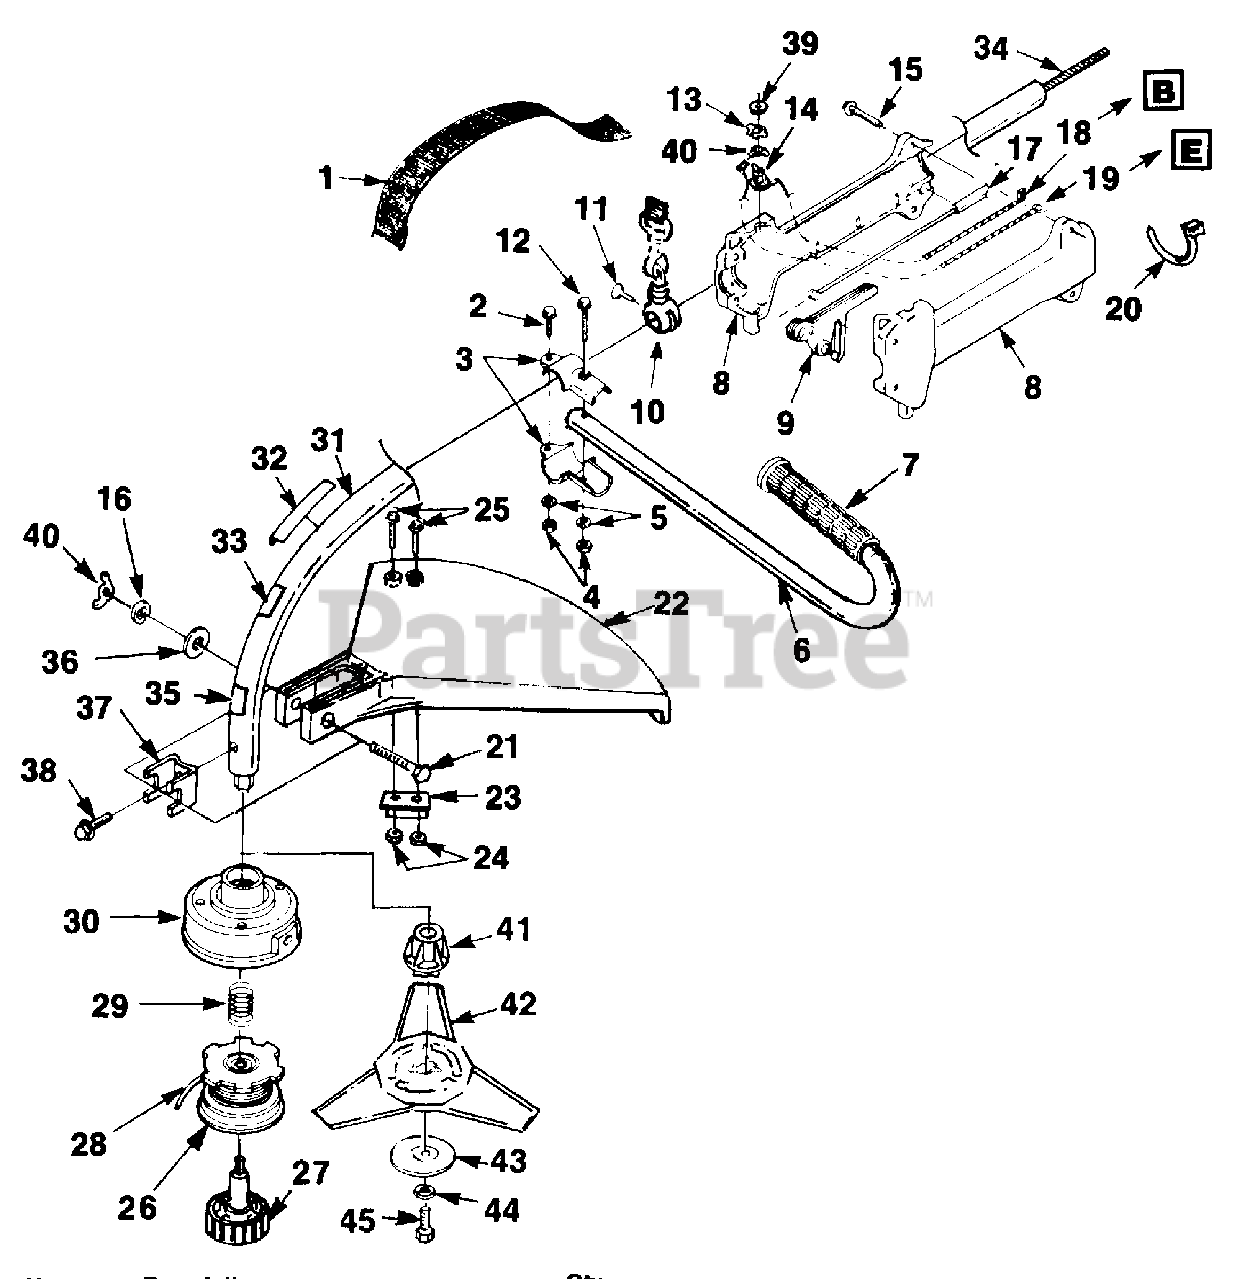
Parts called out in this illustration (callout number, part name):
2	SCREW (1/4-20 x 7/8")
3	CLAMP- Handle bar
4	NUT (1/4-20)
5	WASHER (1/4")
6	HANDLE BAR
8	HANDLE GRIP ASSY.
9	TRIGGER
10	BRACKET- Hanger
11	SCREW-Thumb (10-24 x 1/2")
12	SCREW (1/4-20 x 1 1/2")
13	PLATE- Indicating
14	SWITCH- Toggle
15	SCREW- Plastite (#8 x 3/4")
16	WASHER- Lock (1/4")
17	CABLE- Throttle
18	LEAD- Electrical
19	LEAD- Ground
20	CABLE- Tie
21	SCREW (1/4-20 x 2")
22	DEFLECTOR- Grass
23	BLADE- Cut off
24	NUT (10-24)
25	SCREW(10-24 x 7/8")
26	SPOOL & STRING
27	RETAINER
28	LINE- Replacement (.095)
29	SPRING- Compression
30	HOUSING & EYELET
31	HOUSING- Driveshaft
33	DECAL
34	SHAFT- Flexible
35	DECAL- Warning
36	WASHER- Flat
37	CLAMP
38	SCREW (10-24 x 1/2")
39	NUT- Toggle Switch
40	NUT- Wing
41	ADAPTOR- Blade
42	TRI-ARC BLADE
43	WASHER- Cupped
44	WASHER- Lock
45	SCREW- Machine
